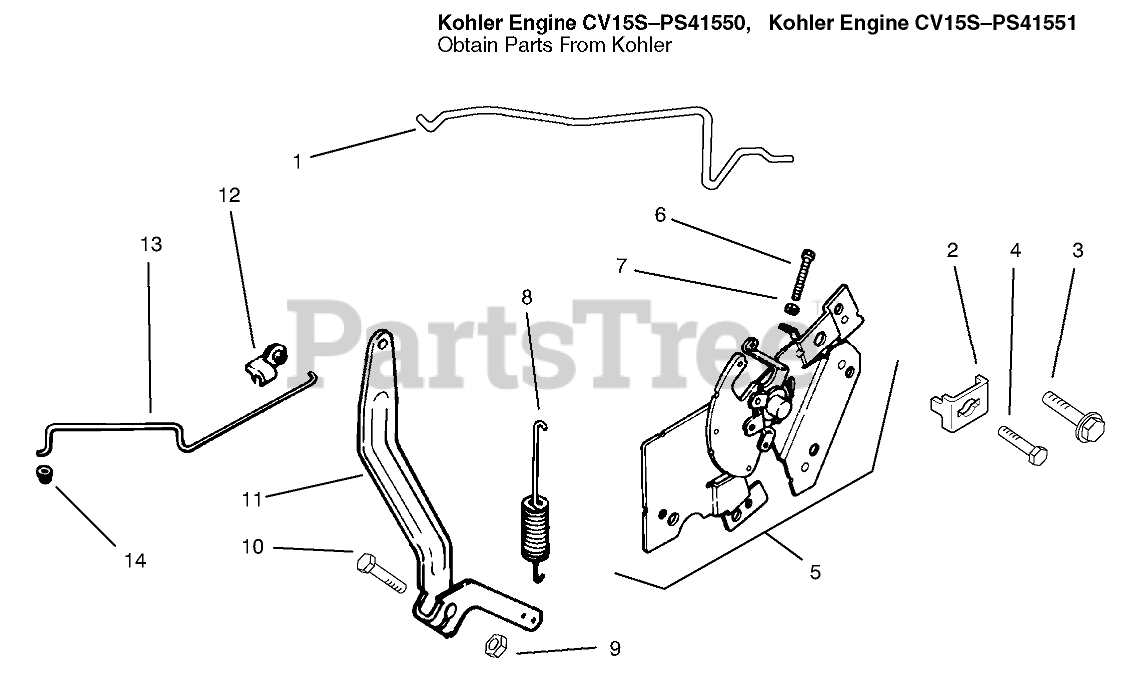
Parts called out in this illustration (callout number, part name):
1	Linkage Choke
2	Clamp
3	Screw Socket
4	Screw-HF
5	Control-Speed ASM
6	Screw
7	Nut
8	Spring-Governor
9	Nut
10	Screw
11	Lever-Governor
12	Bushing-Linkage
13	Linkage-Throttle
14	Bushing-Linkage
